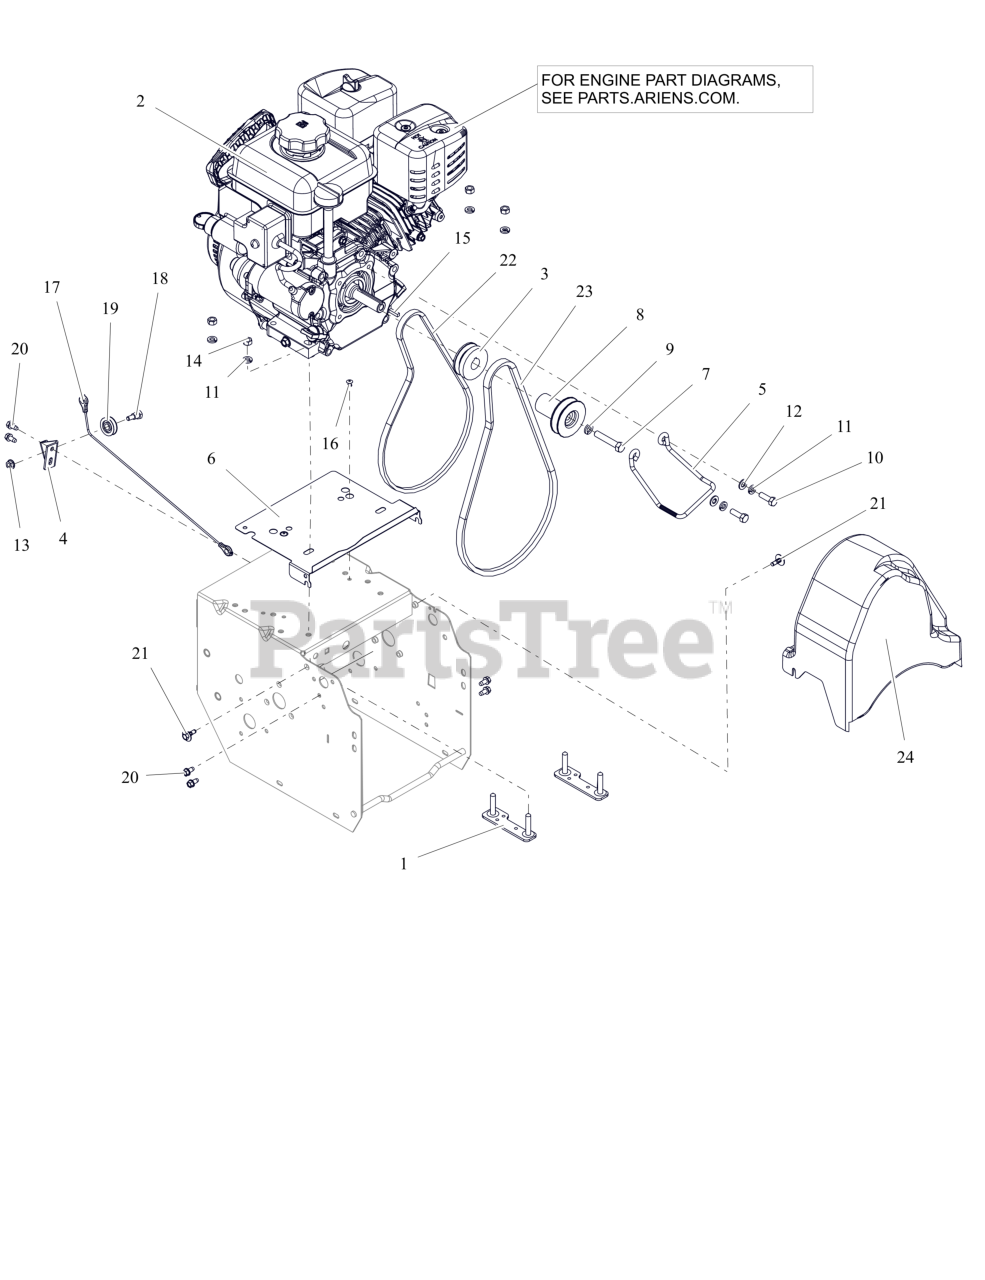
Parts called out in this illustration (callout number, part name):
1	STRAP, ENGINE BOLT-WELDMENT
2	ENGINE, AX179 ALL SEASON
3	PULLEY, TRACTION
4	BRACKET, CABLE PULLEY
5	BELT FINGER
6	BAFFLE, COMPACT
7	BLT, HEX .38-24X2.00 G5 ZCC
8	SHEAVE, AUGER DRIVE
9	WSHR,LK-REG .375X.094 ZCC
10	BLT, HEX 0.3125-24X1 G5 ZCC
11	WSHR, LK-HVY .312X.097 ZCC
12	WSHR,FLT .344X.688X.065 ZCC
13	NUT-LK-CTR-FLG .25-20 ZC120
14	NUT, HEX .312-18 ZCC
15	KEY-SQ .188X.75X.188
16	RVT, POP .1875 ZCC
17	CABLE, LOWER TRACTION (DELUXE)
18	BOLT, SHLDR -.375 X .375 X .25-20
19	PULLEY, CABLE
20	SCR-TAP .25-20X.50 HWH ZCC
21	SCR-TAP .25-20X.5 CAPTIVE
22	V-BELT, 3L-WRAPPED
23	V-BELT, HA-RAW EDGE
24	BELT COVER
